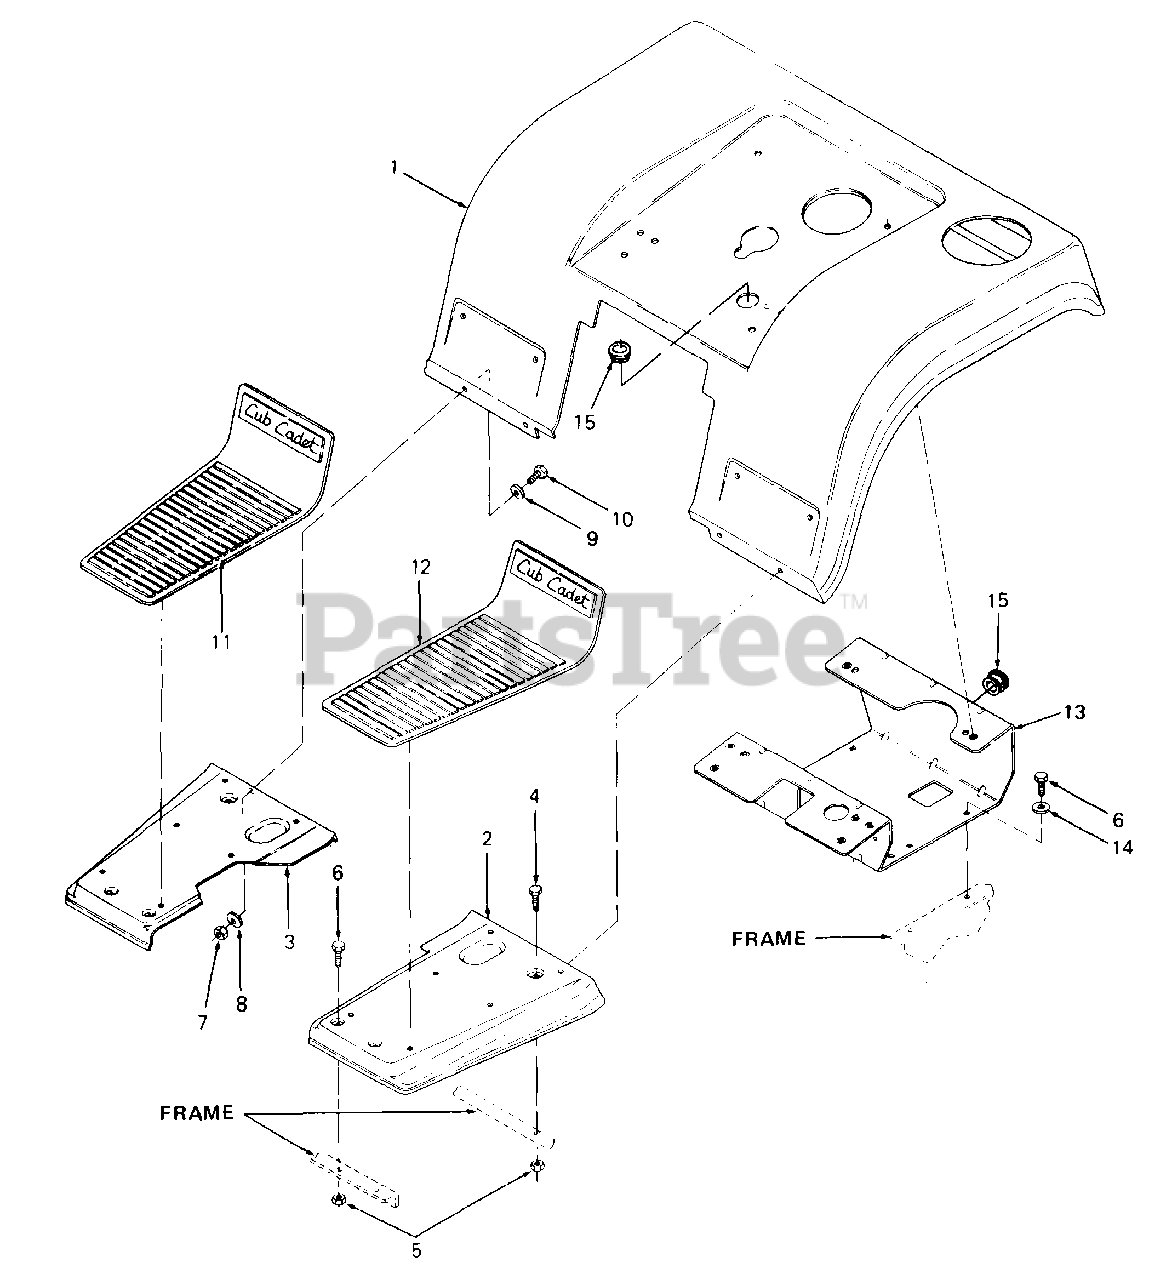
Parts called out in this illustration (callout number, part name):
5	Nut, Hex Center Lock, 5/16-18 GR5
6	Screw, Hex Cap, 5/16-18 X .62 Lg GR5
7	Nut, Hex Patch Lock, 1/4-20
8	Washer, Bell, .265 X .75 X .062 Thk
9	Washer, Flat, .281 X .73 X .063 Thk
10	Screw, Hex, Cap, 1/4-20 X .50 Lg GR5
11	Foot Pad - RH
12	Foot Pad - LH
14	Washer, Flat, .34 X .68 X .062 Thk
15	Bushing, Snap
